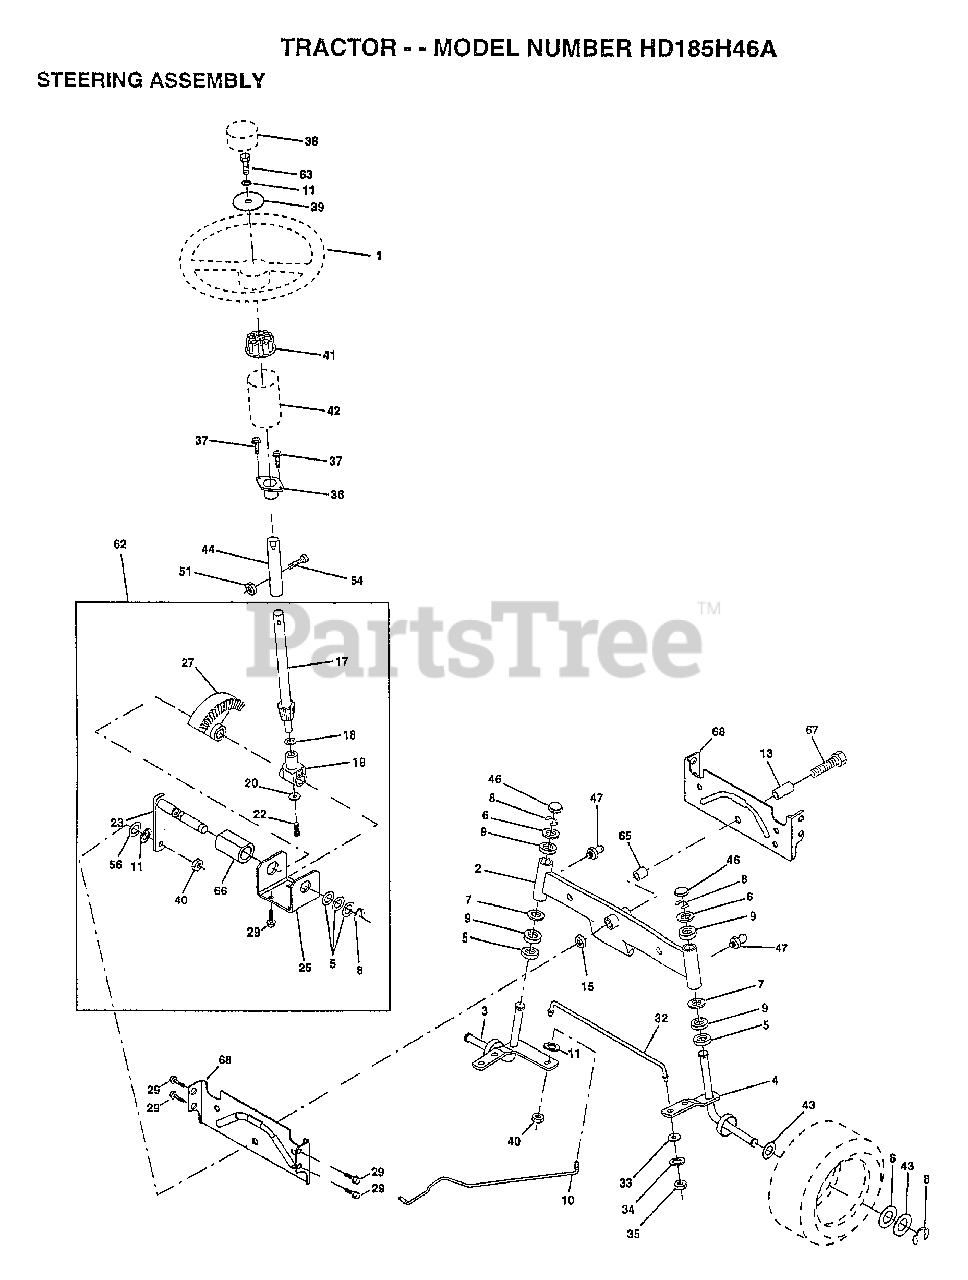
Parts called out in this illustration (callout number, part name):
1	WHEEL STR AYP BLK
2	AXLE ASM
3	"SPINDLE ASM, LH"
4	SPINDLE ASM RH
5	WASHER .T
6	WASHER
7	WASHER
8	RING
9	COL. SRTG. BEAR.
10	DRAGLINK-STAMPED
11	LOCKWASHER
13	BEARING AXLE
15	"NUT-LOC,FLANGE LT"
17	SHAFT ASM STEERIN
18	THRUST WASHER
19	SUPPORT.SHAFT
21	LOCKWASHER
22	SCREW.SCKTHD.CAP
25	BRKT-STEERING
27	GEAR SECTOR
29	SCREW
32	ROD.TIE.19.75
33	WASHER M
34	LOCKWASHER
35	NUT.LOCK.5/16-24
36	BUSHING.STEERING
37	"SCREW-TT,10-32 FL"
38	CAP STEER AYP
39	WASHER T
40	GRIPCO NUT
41	ADAPTER LT
42	BOOT.STEER.PL
43	WASHER
44	EXT SHAFT STEERIN
46	CAP
47	ZERK M
51	NUT
54	BOLT
56	WASHER
62	KIT STEERING ASM
63	BOLT
65	SPACER AXLE
66	"BEARING-ARM,PITMA"
67	BOLT
68	BRACE AXLE
